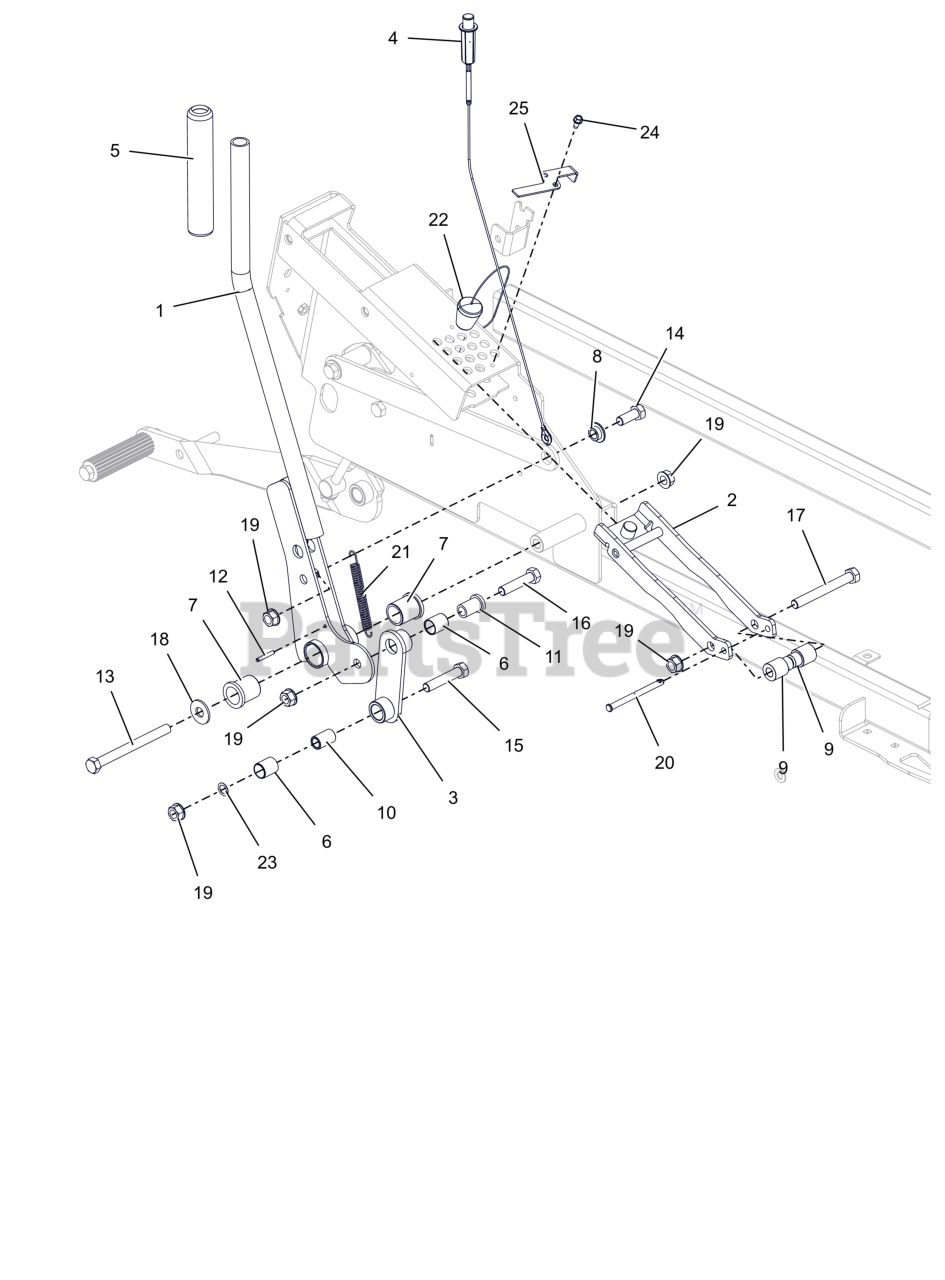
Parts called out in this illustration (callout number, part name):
1	WLDMT, HOC LEVER
2	WLDMT, HOC BRACKET
3	LINK, HOC LEVER
4	CABLE, HOC PUSH CONTROL
5	GRIP, DECK LIFT
6	BRG, .750 X .875 X 1.000
7	BSHG-FLG 1.00X1.25X1.50X1.50
8	BSHG, FLG .515X.750X.360X1.12
9	BSHG,FLG
10	SPCR, SLV .532 X .750 X 1.150
11	BSHG-FLG .515X.746X1.290X1.000
12	PIN-ROLL .188X1.25
13	BLT,HEX .50-13X5.50 G5 ZCC
14	BLT,HEX .50-13X1.25 G5 ZCC
15	BLT, HEX .50-13X2.50 G5 ZCC
16	BLT, HEX .50-13X2.25 G5 ZCC
17	BLT, HEX 0.5-13X4.25 GR5 ZCC
18	WSHR,FLT .563X1.375X.109 ZCC
19	NUT-LK-CTR-FLG .500-13 GG ZCC
20	PIN, SLIC-.3125X4.015X3.625 -ZCC
21	SPRING,EXT,.061X.50X3.0
22	PIN, MAGNETIC .50X2.50
23	WASHER, .500X.750X.020 THRUST
24	SCR-TAP .25-20X.50 HWH ZCC
25	BLOCK, HOC SELECTION (BLACK)
